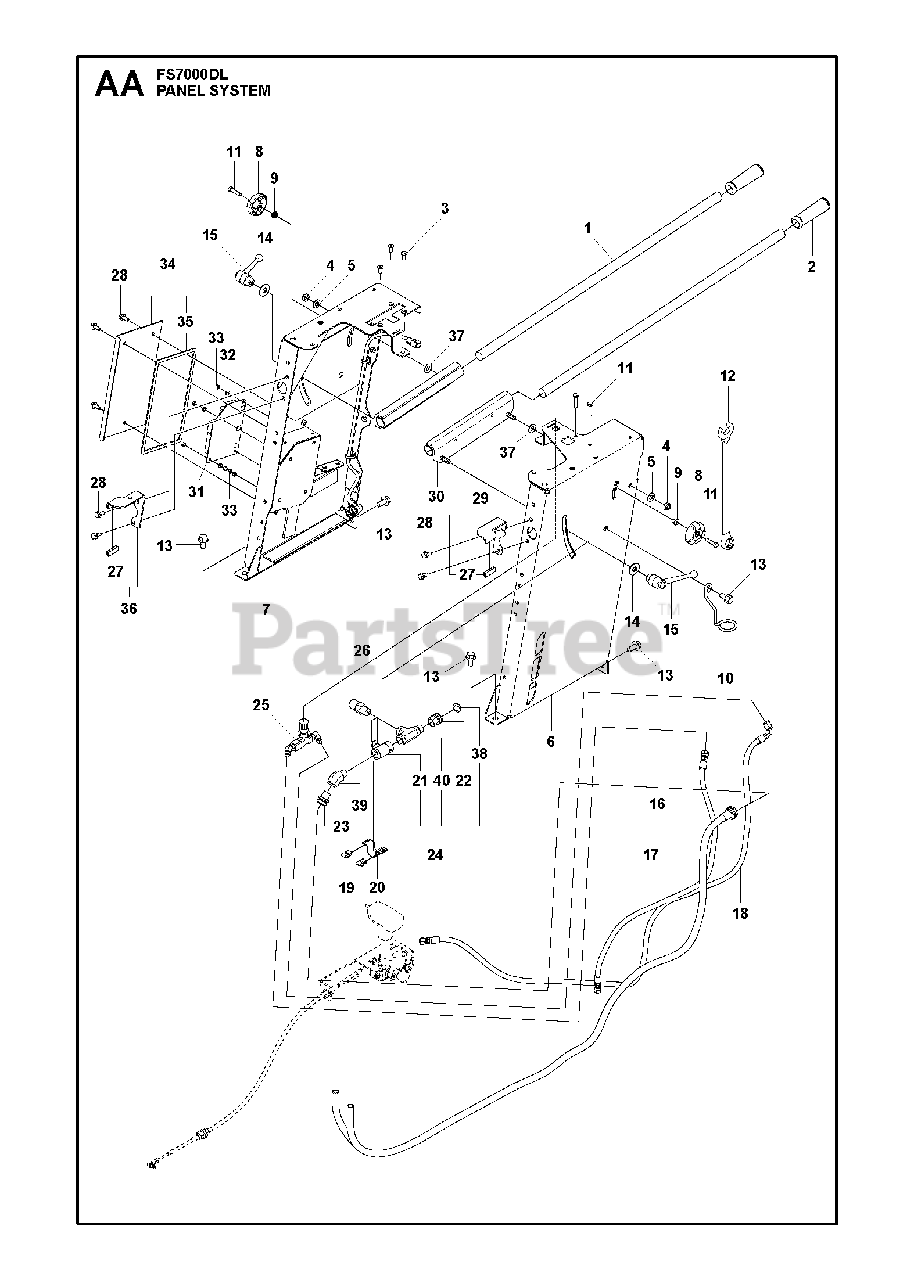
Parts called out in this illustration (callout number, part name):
5	WASHER
8	TURNING KNOB
9	HEXAGON NUT FLANGE
37	WASHER, FRICTION 1/2 X 1" OD
